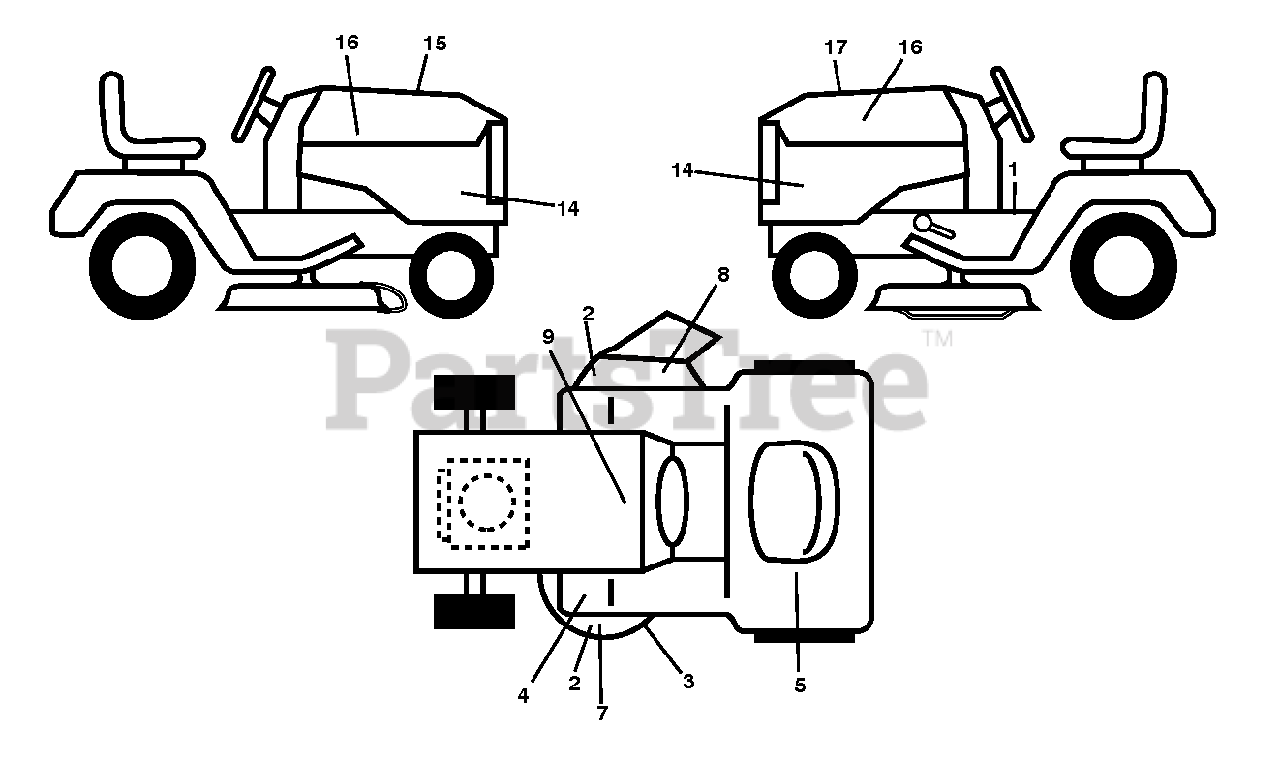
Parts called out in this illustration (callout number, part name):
1	DECAL.FENDER.WARNING
2	DECAL.DECK.6MIL.EURO.NOSTEP
3	DECAL.MOWER.SCH.48/54
4	DECAL.PEDAL.HUSQ.CROWN
5	DECAL.RESERVEFUELSELCTR.ENG
7	DECAL.HV.REINFORCED.DECKS.2012
8	DECAL, DECK DEFLECTOR, WARNING
9	DECAL BTRY SYMBOLS
14	DCL.SDPNL.HUSQGT2.GT52XLS.SET
15	DECAL.WARNING.CUST.RESP.E85.
16	DECAL.BADGE.170MM.TEXTLOGO.
17	DECAL.RPL.KOH.KT7.TLB.52F.G730
